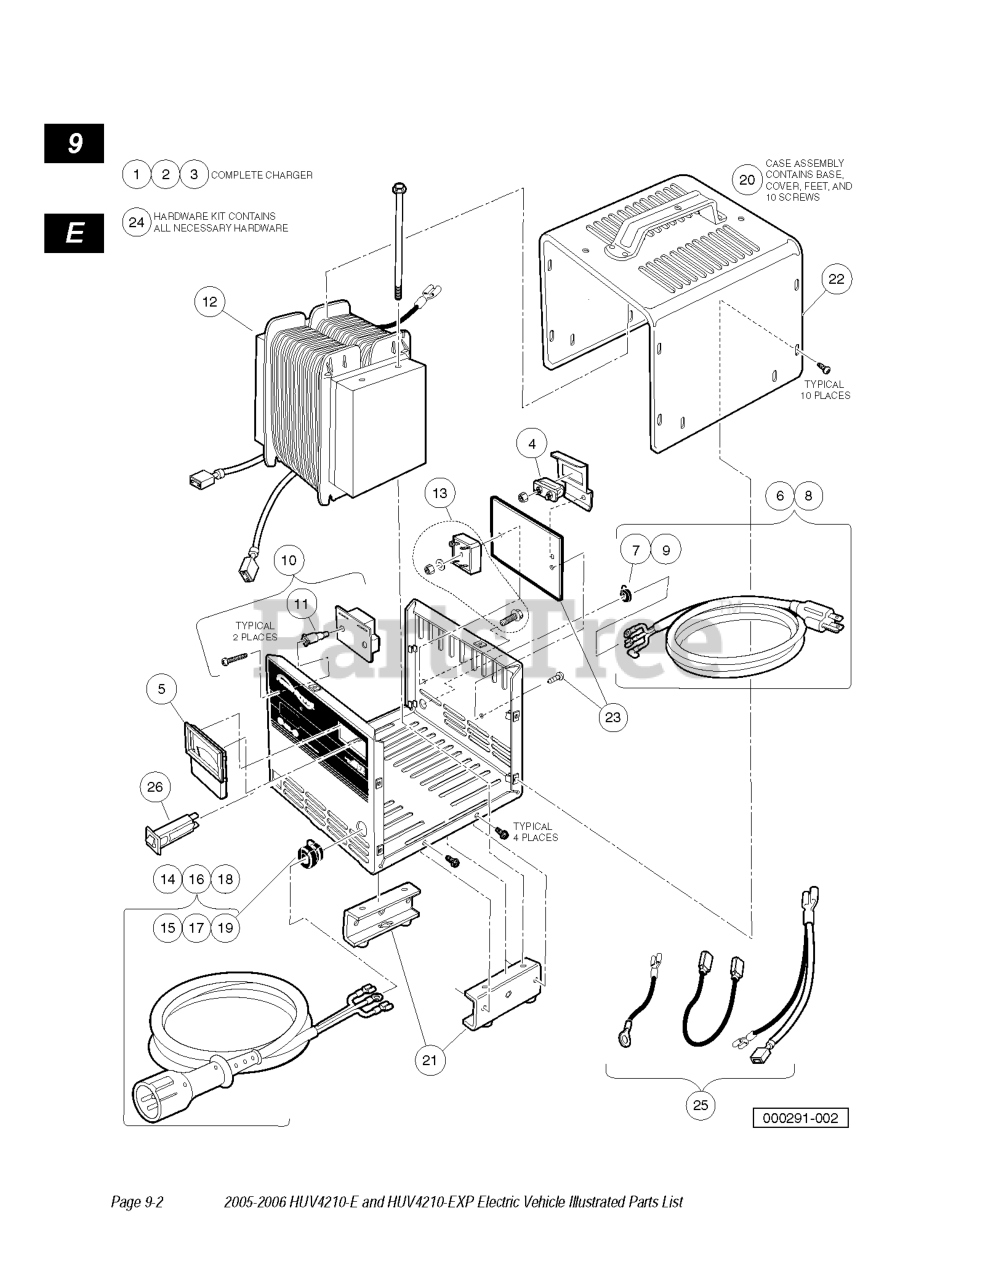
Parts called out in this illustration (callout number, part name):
1	Charger, Pd3, 9Dc/6'Ac'
2	CHARGER, PD3, 12' DC/ 9' AC
3	CHARGER, PD3, 20' DC/ 9' AC
4	PD2 FUSE ASM
5	PD2 AMMETER
6	Kit, PD3 Cordset - AC 80"
7	PD2 AC CORD BUSHING
8	Kit, PD3 Cordset, - AC 114"
9	PD2 AC CORD BUSHING
10	PD3 BOARD ASSY, RELAY
11	PD3 Plastic Stand-Offs
12	PD3 Transformer
13	PD3 DIODE BRIDGE
14	PD3 Cordset - DC 113"
15	DC CORD BUSHING
16	PD3 Cordset - DC 154"
17	DC CORD BUSHING
18	PD3 Cordset - DC 205"
19	DC CORD BUSHING
20	Asm, PD3 Case
21	Asm, PD3 Legs
22	PD3Case Top
23	Kit, PD3 Heat Sink
24	Kit, PD3 Hardware
25	Kit, PD3 Wires
26	CIRCUIT BREAKER, 15A/120V
